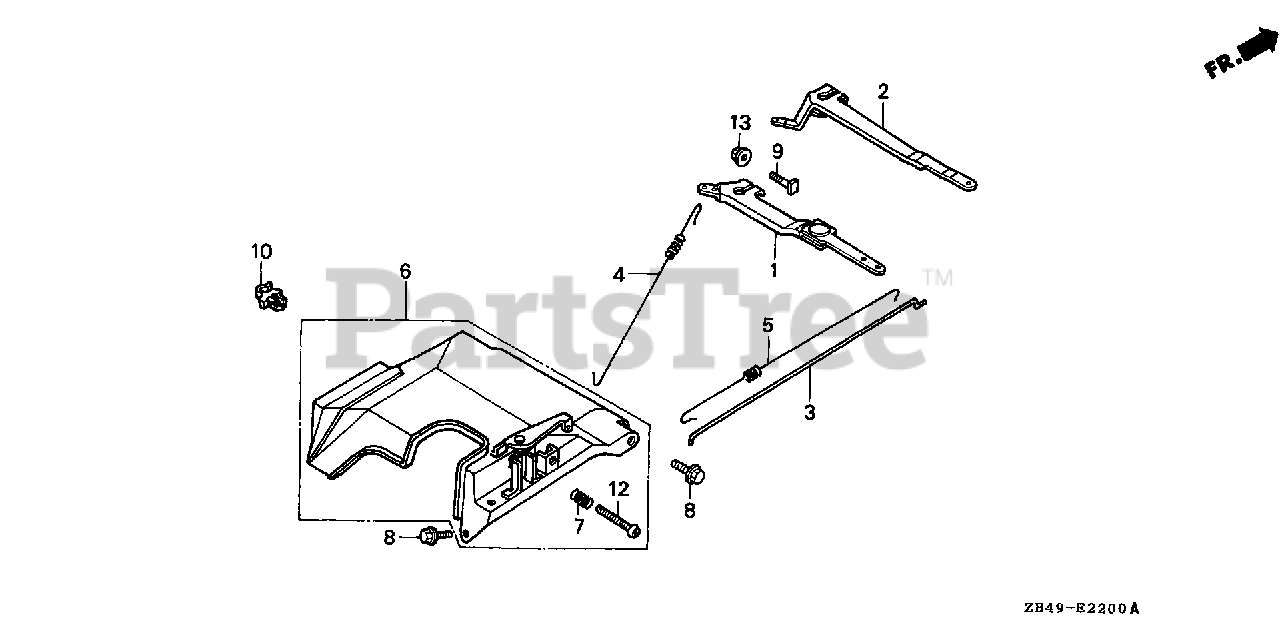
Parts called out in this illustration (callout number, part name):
2	ARM, GOVERNOR
3	ROD, GOVERNOR
4	SPRING, GOVERNOR (L=145.0MM) (WIRE DIAMETER 1.0MM)
5	SPRING, THROTTLE RETURN
6	CONTROL ASSY.
7	SPRING, CONTROL ADJUSTING
8	BOLT, FLANGE (6X12) (CT200)
9	BOLT, GOVERNOR ARM
12	SCREW, PAN (5X35)
13	NUT, FLANGE (6MM)
